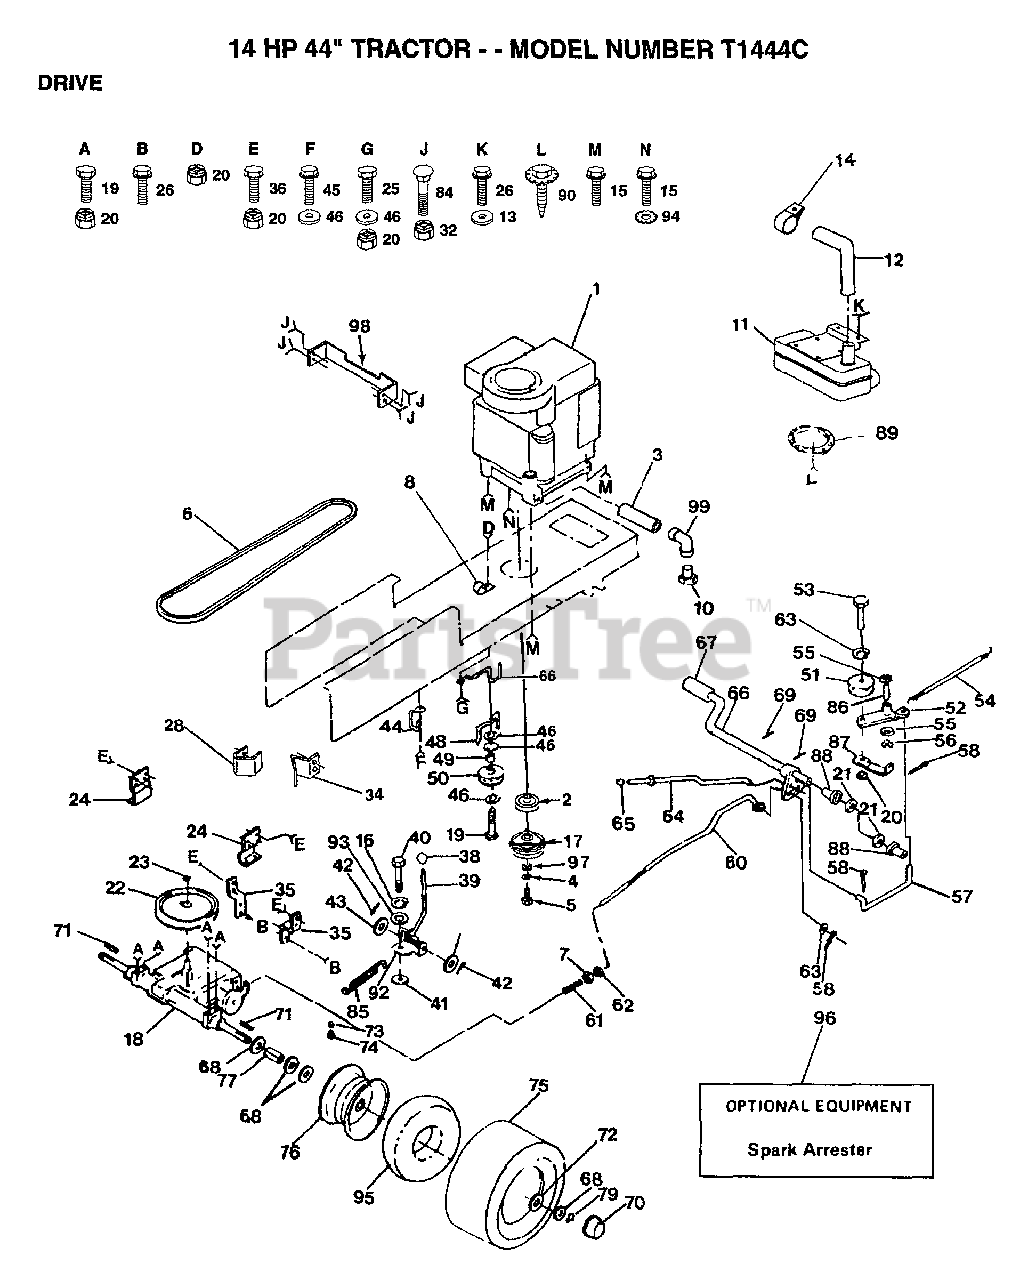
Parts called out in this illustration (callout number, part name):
3	PIPE NIPPLE
4	LOCKWASHER
7	NUT
8	CLIP T
9	KEEPER BELT ENGLH
12	"TUBE,EXHAUST"
13	WASHER
14	"CLAMP,MUFFLER"
15	SCREW
16	LOCKWASHER
19	BOLT
21	WASHER LT
22	PULLEY TRANS
24	BRACKET LT
25	BOLT
26	SCREW
28	"KEEPER,BELT LH T"
34	"KEEPER,BELT RH T"
35	STRAP TORQUE
38	CONTROL KNOB LT
39	ROD SHIFTER
41	WASH-SHFT PLT LT
42	PIN COTTER 1/8
43	WASHER
45	SCREW
46	WASHER
48	BELT KEEPER LT
49	SPACER T
50	PULLEY.IDLER.FLAT
52	ARM IDLER
54	"SPRING, RETURN LT"
55	WASHER LT
56	KLIP RING
57	"LINK, CLUTCH T"
58	COTTER PIN
61	SPRING ROD LT
62	NUT
63	WASHER
64	PARKING BRAKE ROD
67	PEDAL COVER T
68	WASHER
70	HUB CAP
71	SQUARE KEY
72	WASHER
73	VALVE CAP
74	VALVE STEM LT
77	SPACER LT
79	E-RING LT
84	BOLT
86	"LY, BEARING"
87	RETAIN BELT
88	NYLON BEARING
89	DEFLECTOR.222573
92	PLATE SHIFT LT
93	WASHER LT
94	LOCKWASHER
95	TUBE.18X9.5-8
96	SPARK ARREST KIT
97	WASHER
99	ELBOW
